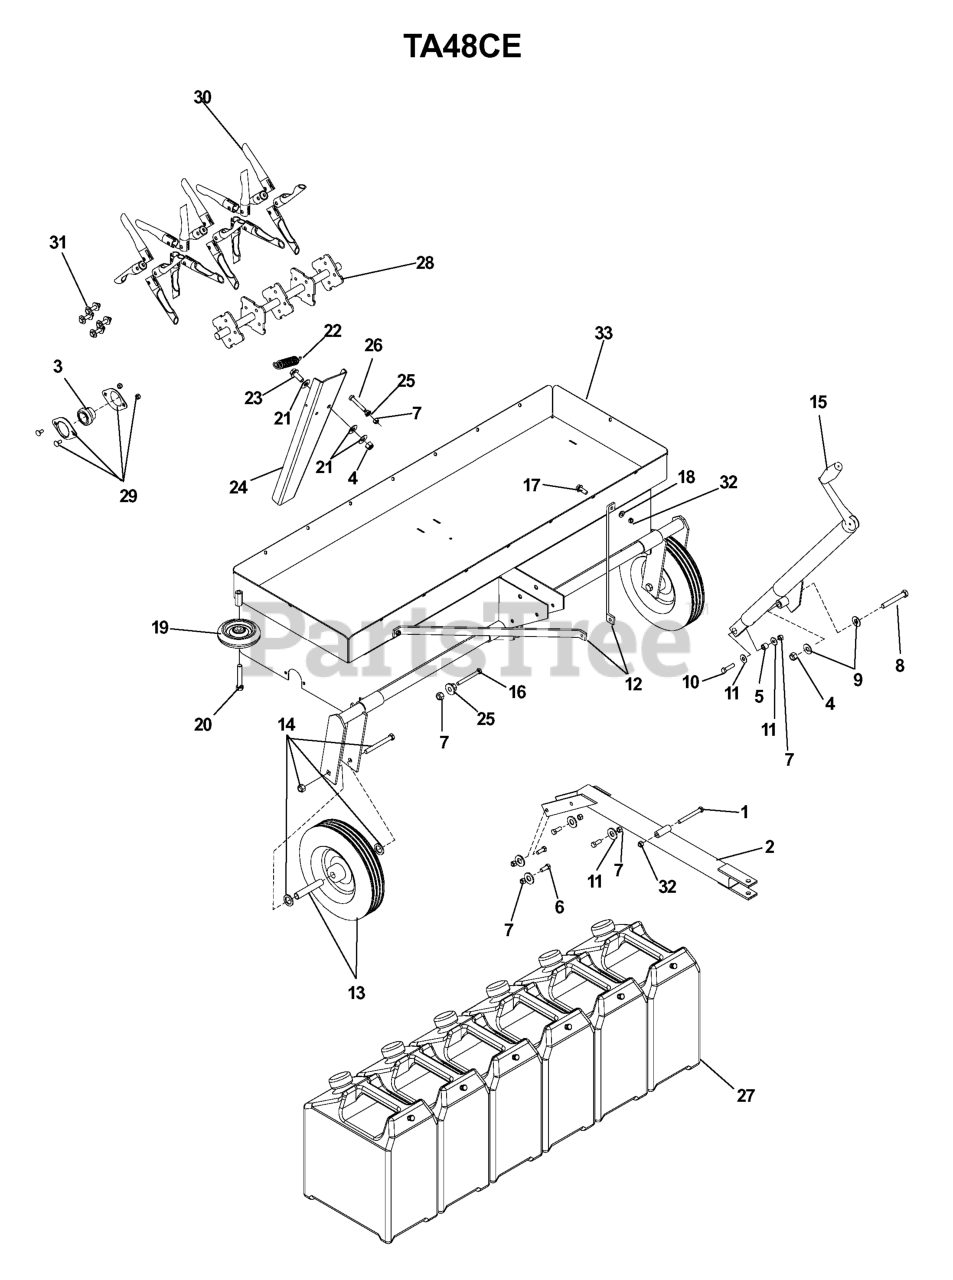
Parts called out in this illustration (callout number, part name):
1	HCS 5/16 X 3
2	TONGUE, BLACK
3	BRG 1" W/LOCKING COLLAR
4	NUT 1/2-13 HEX NYLOC ZD
5	BUSHING, AXLE PIVOT
6	HCS 3/8-16X1.GRD.5.ZD
7	NUT 3/8-16 NYLOC
8	HCS 1/2-13 X 3-1/2 GR 5 ZD
9	WASHER 1/2 FLAT
10	HCS 3/8-16 X 1 3/4 GR5
11	WASHER 3/8 FLAT
12	TIE BAR, BLACK
13	WHEEL.12X3.W/ROLLER.BEARING
14	BOLT KIT
15	JACK, BLACK
16	HCS 3/8C X 3 1/2
17	RHSNB 5/16C X 1
18	WASHER 5/16 FLAT
19	WHEEL, 1 1/4X5 TOW AER
20	SCREW, 1/2C X 3 HEX CAP
21	WASHER 7/16 FLAT ZD
23	HCS 1/2C X 1 1/4 SERRATED HEAD
24	KICKSTAND, BLACK
25	NUT 3/8C WHIZ
26	HCS 3/8C X 2 1/4
27	WATER TANKS (SET OF 6)
28	ROTOR, BLACK
29	STAMPING KIT 1" BRG
30	TINE SET, 20 TINES
31	FASTENER KIT, 1 ROTOR
32	NUT 5/16 NYLOC
33	FRAME, ORANGE
